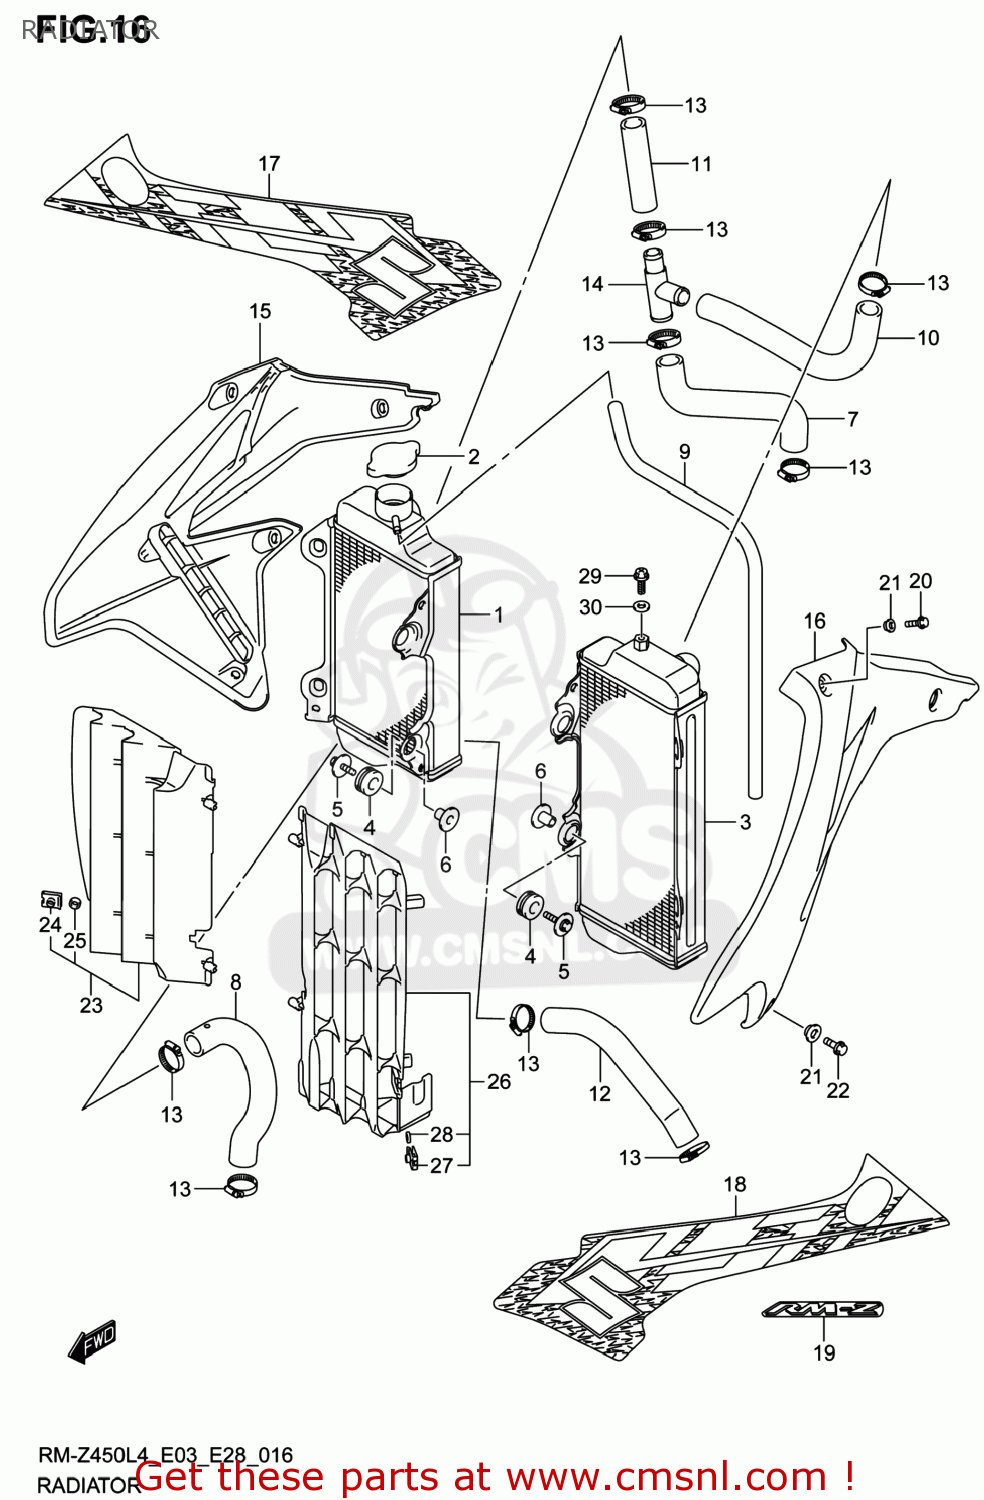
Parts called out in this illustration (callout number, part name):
1	RADIATOR,WATER,R
2	CAP,RADIATOR
3	RADIATOR,WATER,L
4	CUSHION,RADIATOR LWR
5	BOLT(6X25)
6	SPACER(6.5X10.5X14.1)
7	HOSE,RADIATOR INLET
8	HOSE,RADIATOR OUTLET
9	HOSE(5X8X1000)
10	HOSE,RADIATOR JOINT UPR NO.1
11	HOSE,RADIATOR JOINT UPR NO.2
12	HOSE,RADIATOR JOINT LWR
13	CLAMP
14	JOINT,RADIATOR HOSE
15	COVER,RADIATOR,R
16	COVER,RADIATOR,L
17	TAPE,RADIATOR COVER,R
18	TAPE,RADIATOR COVER,L
19	EMBLEM,RADIATOR COVER
20	BOLT(6X12)
21	WASHER,FR FENDER
22	BOLT
23	LOUVER,RADIATOR,R
24	NUT
25	SPACER(6.2X10X2.2)
26	LOUVER,RADIATOR,L
27	NUT
28	SPACER(6.2X10X2.2)
29	UNION BOLT,AIR VENT
30	GASKET(6.4X11.5X0.8) (NAS)
